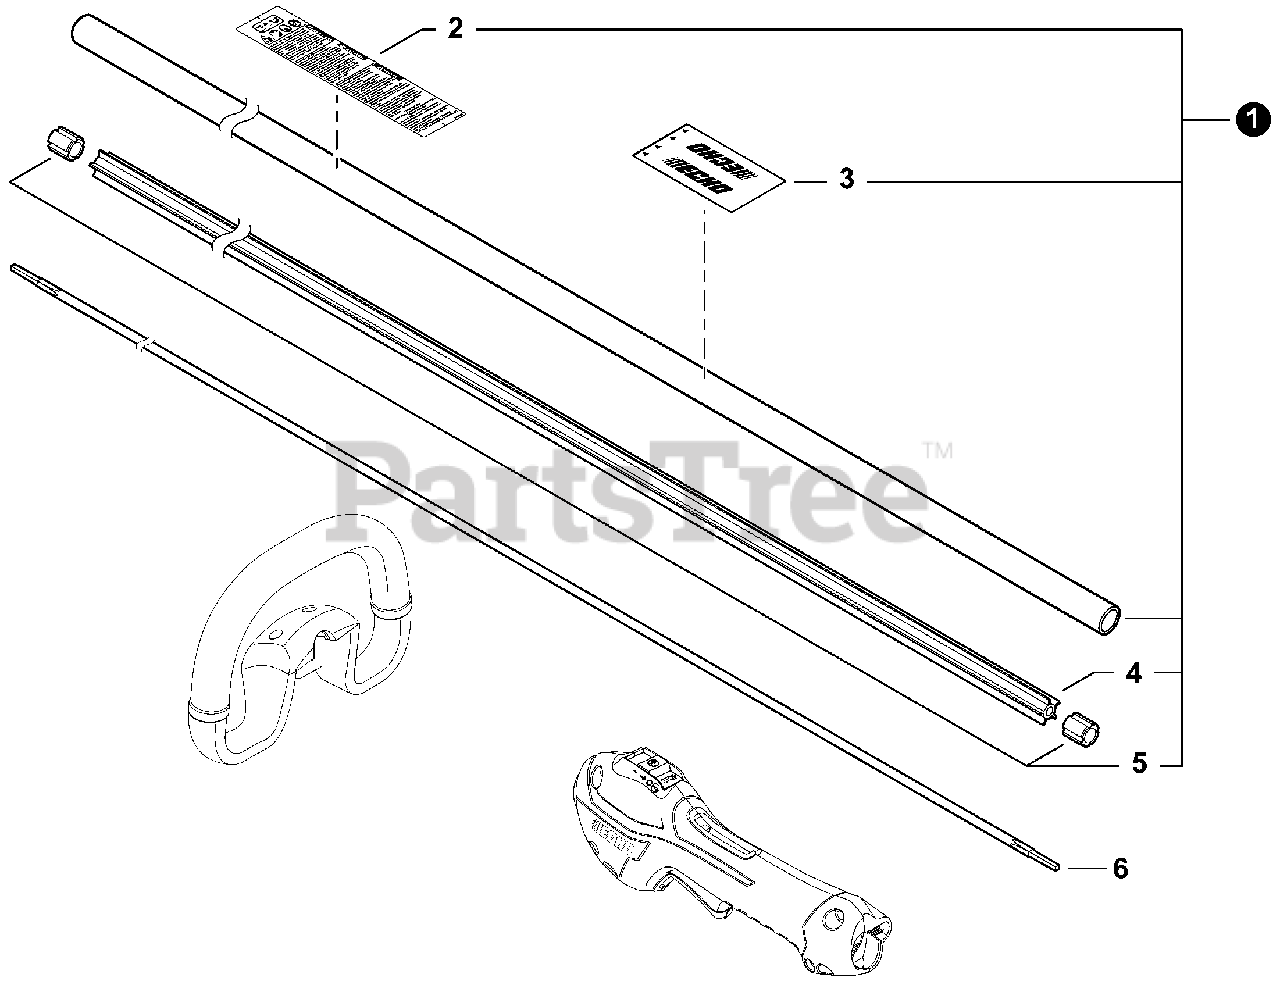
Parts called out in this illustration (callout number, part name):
1	MAIN PIPE ASSY
2	LABEL, CAUTION
3	LABEL, HANDLE LOCATION
4	LINER, FLEXIBLE 21.6×1420
6	DRIVESHAFT - FLEXIBLE
